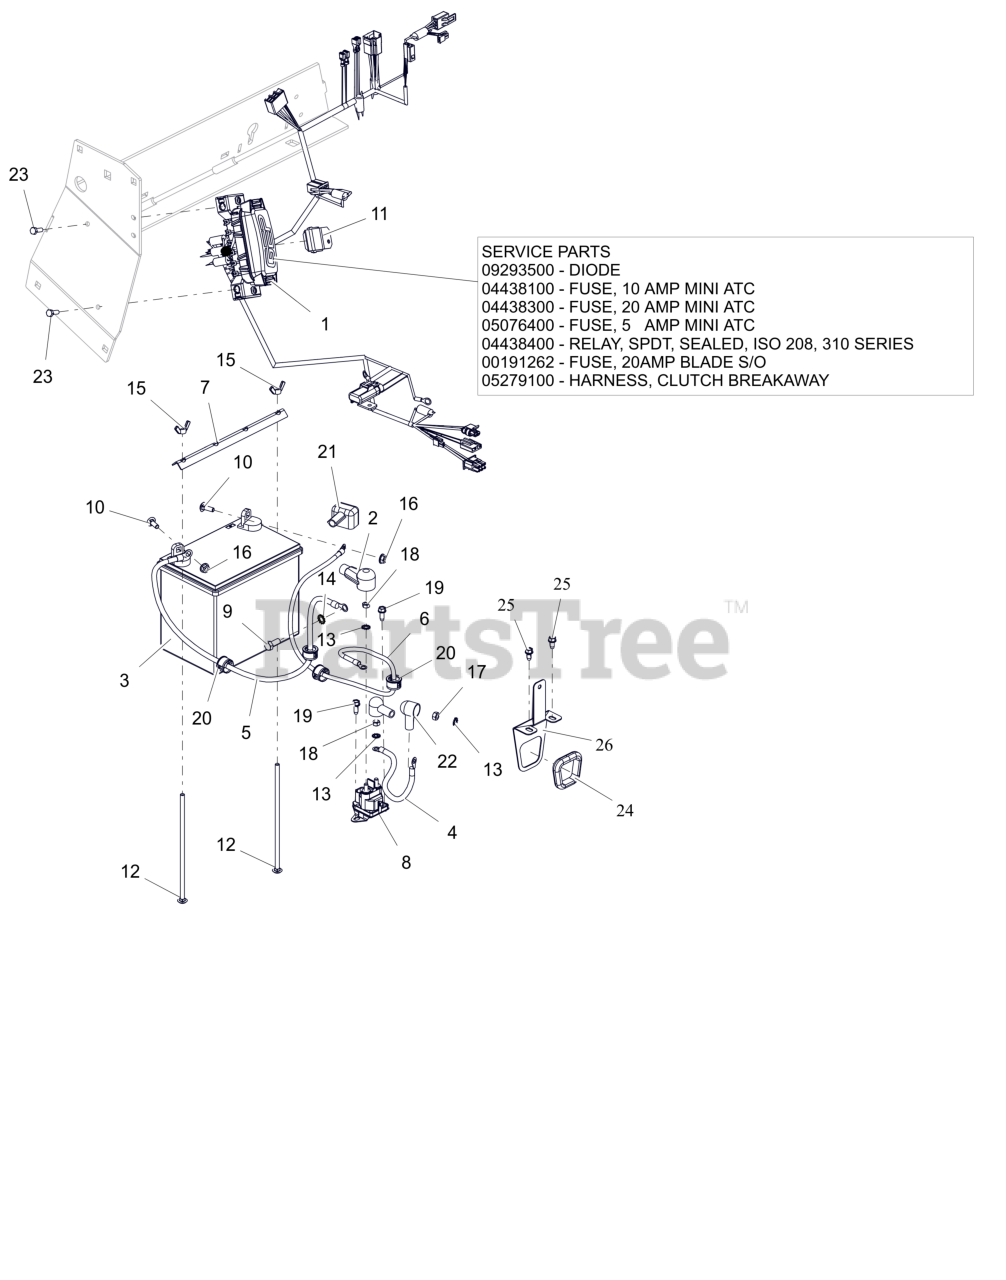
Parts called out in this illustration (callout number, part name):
1	HARNESS, PROSTANCE
1	DIODE, CONNECTOR SHELL
1	FUSE,10 AMP MINI-ATC
1	FUSE,20 AMP MINI ATC
1	FUSE, 5 AMP MINI-ATC
1	RELAY,MICRO5 TERML W/RESISTOR
1	FUSE, 20 AMP BLADE S/O
1	HARNESS, CLUTCH BREAKAWAY
2	BOOT, BATTERY TERMINAL-RED
3	BATTERY, 300 CCA 10U1L
4	CABLE-POSITIVE BATTERY 9.00"
5	CABLE-NEGATIVE BATTERY 24.00"
6	CABLE-POSITIVE BATTERY 26.00"
7	HOLD DOWN
8	SOLENOID, STARTER (SEALED)
9	BLT, HEX M8-1.25X20 G8.8 ZCC
10	BLT, RHSN .25-20X.750 G5 ZCC
11	MODULE,INTERLOCK,DELAY, 1801
12	BTL,RHSN .250-20 X 7.5 G5 ZCC
13	WSHR,LK-EXT.262X.502X.026 ZCC
14	WSHR-LK-EXT 0.326X0.599X0.031 ZCC
15	NUT, LK-WING .25-20 ZCC
16	NUT-SPNLK-FLG .25-20 ZC120
17	NUT-STD .250-20 G2 ZCC
18	NUT-STD M6-1.0 ZCC
19	SCR,TAP .25-20X.625 HWH ZCC
20	BUSH, PANEL SNAP .687X.875X.56
21	INSULATOR
22	BOOT, EYELET TERMINAL
23	BLT, HEX M6-1.0 X 20 G8.8 ZCC
24	GROMMET 1.70ID X 2.0OD
25	SCR-TAP .25-20X.50 HWH ZCC
26	GUARD, CLUTCH HARNESS ROUTING
